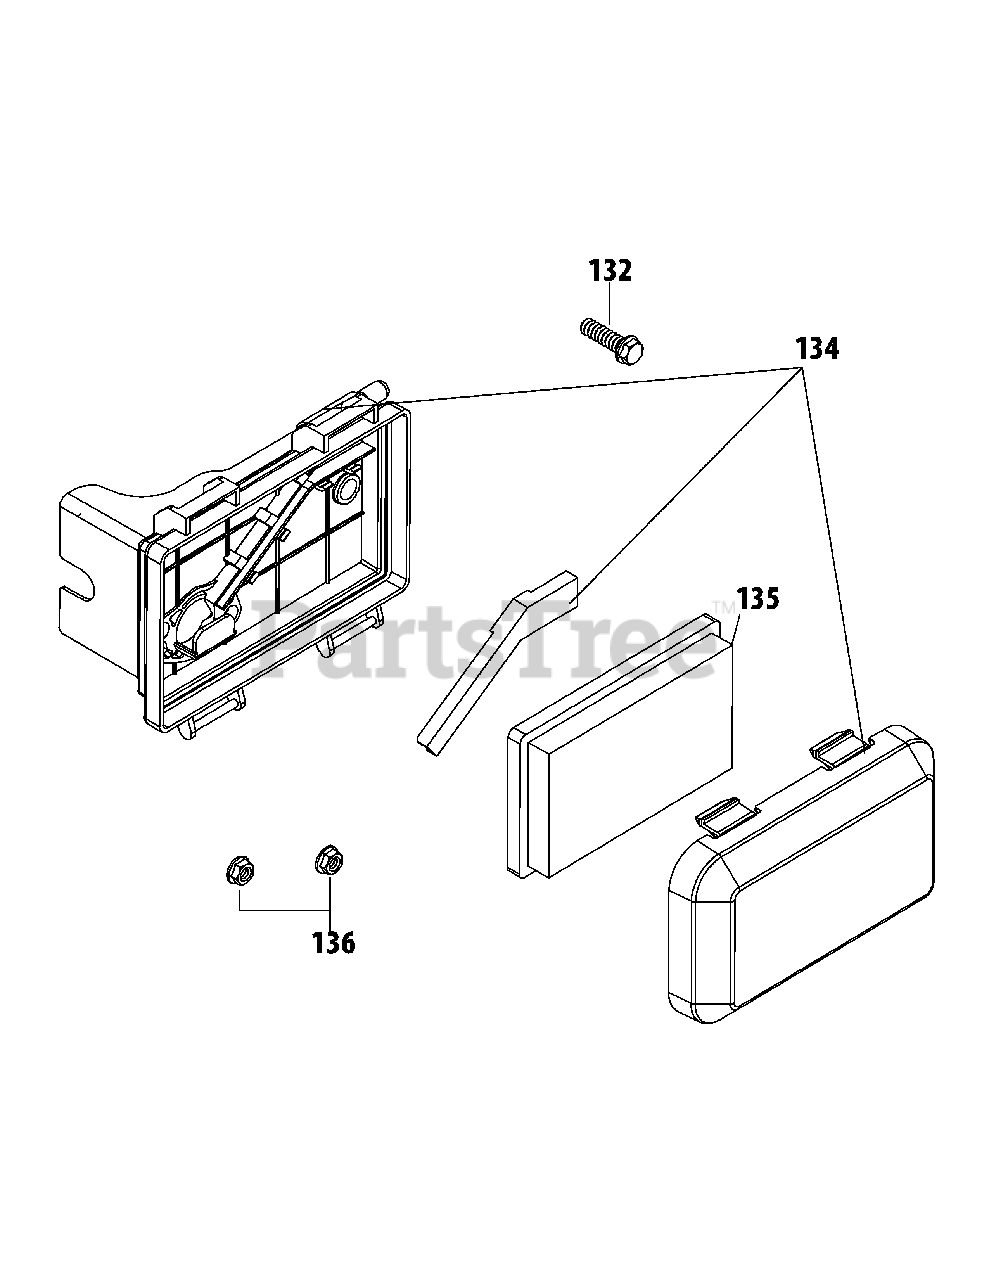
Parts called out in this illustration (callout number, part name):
132	Bolt M6X30 Af Base/Coil/E-Starter
134	Air Filter Cover Kit
135	Air Filter Element, Paper
136	Nut M6X10Mm Starter/Carb/Muff
